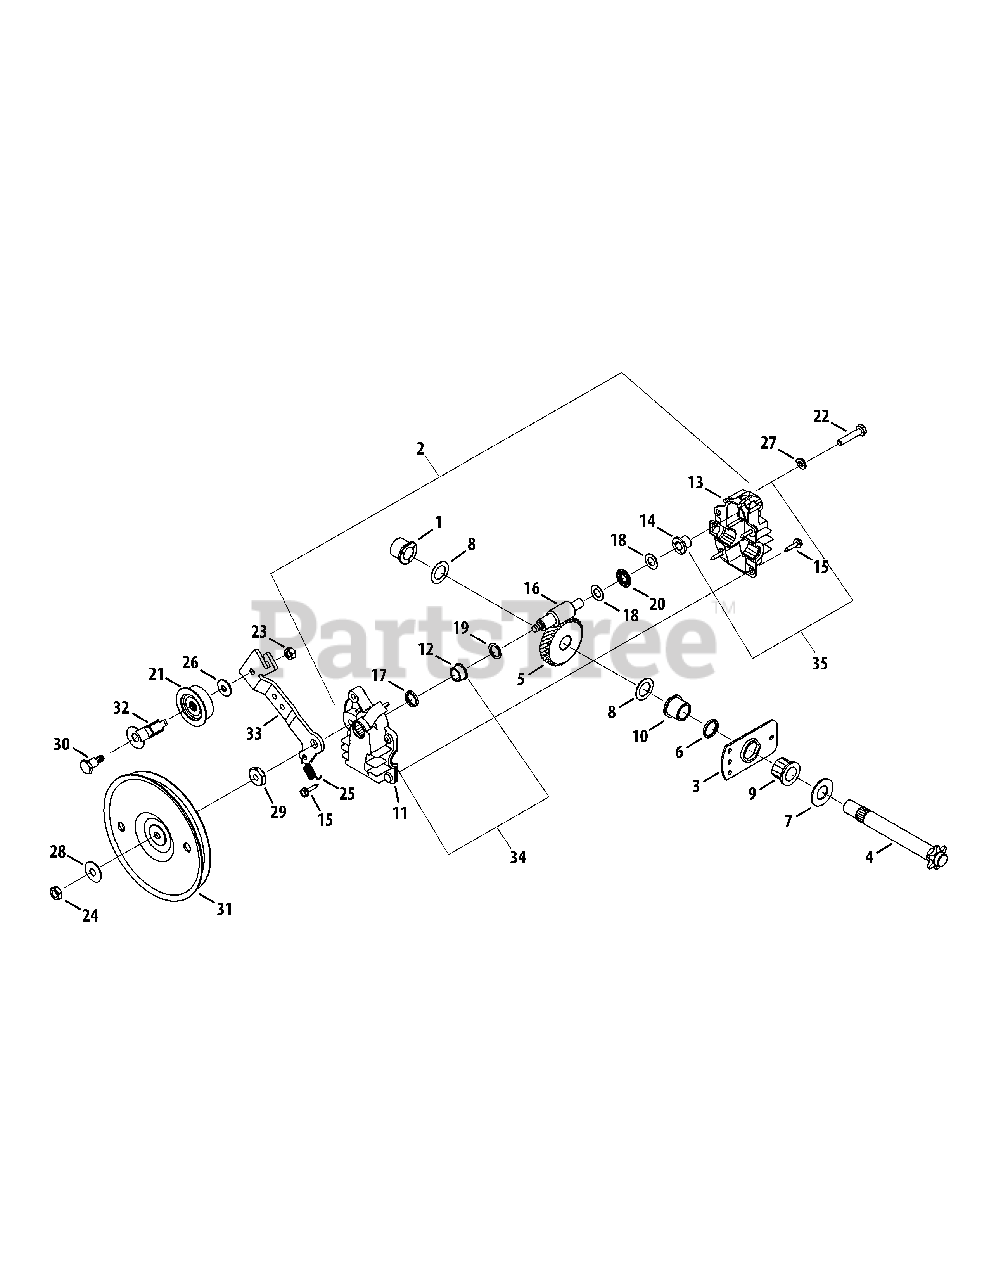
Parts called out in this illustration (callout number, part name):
1	Flange Bearing.566 ID
2	Shredder Transmission Assembly
3	Hex Bearing Cup
4	Output Shaft 6T Sprocket
5	Helical 34T Gear
7	Flat Washer, .64 ID x 1.24 OD
8	Flat Washer, 5/8 x 1.0
9	Hex Flange Bearing, .631 ID
10	Flange Bearing, .629 ID
11	Lower Housing
12	Flange Bearing, .503 ID
13	Upper Housing
14	Flange Bearing, .378 ID
15	Hex Washer Screw, #10-16 x.75
16	Pinion Shaft 10T
18	Thrust Washer, .382 ID x.684 OD
19	Flat Washer, .504 ID x.70 OD
20	Thrust Bearing, .375 ID x.812 OD
21	Idler Pulley Assembly W/ Bearing
21	Idler Pulley Only
21	Needle Bearing Only
22	Hex Cap Screw, 1/4-20 x 1.25
23	Hex Nut, 1/4-28
24	Hex Jam Nut, 5/16-24 LH Thd
25	Extension Spring, 1.12 Lg
26	Bell Washer, .265 ID x.75 OD
27	Lock Washer, 1/4
28	Bell Washer, .325 ID x.930 OD
29	Shoulder Spacer, .375 ID x.165 OD
30	Shoulder Bolt, 1/4-28 x.375
31	Flat Pulley 5.06 Dia
32	Belt Keeper
33	Idler Bracket
34	Lower Housing Assembly
35	Upper Housing Assembly
